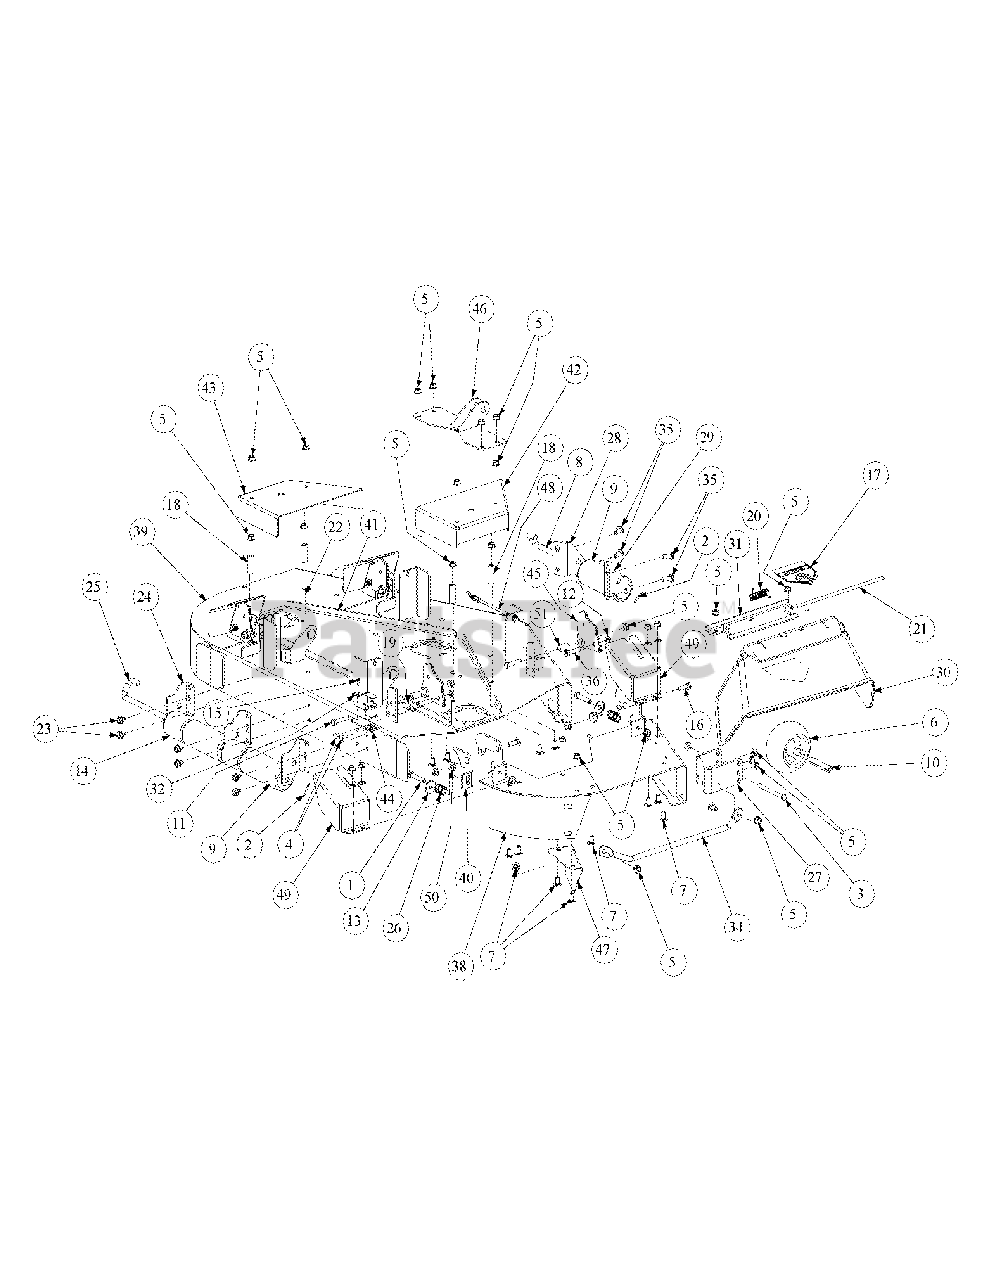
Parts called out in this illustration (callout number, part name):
1	Hex Cap Screw 3/8-16 x 2.00
2	Cotter Pin, .125 Dia. x 1.0
3	Hex Cap Screw, 3/8-16, 3.75
4	Carriage Bolt, 1/4-20 x .750
5	Hex Nut Flange Lock, 3/8-16
6	Complete Wheel, 5.00 Dia
7	Carriage Bolt, 3/8-16 x .75 Lg
8	Roller Pin, 1/2 Dia x 7.31 Lg
9	Front Roller
10	Wheel Spacer
11	Hex Cap Screw, 3/8-16 x 1.750
12	Hex Flange Lock Nut, 5/16-18
13	Flat Washer, .411 x 1.25 x .100
15	Screw, TT, 10-24, .5
16	Carriage Screw, 3/8-16 x 1.25
17	Decal, Danger Hands and Feet
18	Spacer, .39 x .63 x 1.75
19	Nut, 1/4-20, Hex Flange Lock
20	Torsion Spring, 0.4 ID x 2.16 LG
21	Chute Deflector Rod
22	Carriage Bolt, 3/8-16, 2.75
23	Hex Index Washer Screw, 3/8-16, .05
24	Fabricted Deck Roller Mount Bracket
25	Roller Rod
26	Lift Handle Spring
27	Front Anti-Scalp Wheel Mount Bracket
30	Deflector Chute
31	Chute Deflector Bracket
32	Spring Retainer
33	Push Retainer, 3/8
34	Fabricated Deck Finger Guard
35	Self Tapping Screw, 3/8-16 x 0.875
36	Shoulder Bolt 3/8 x 1.50
37	Fab Fold Deck Weldment
38	Fab Fold Wing Weldment, RH
39	Fab Fold Wing Weldment, LH
40	Pull Fold Hinge Lock
41	Deck Stiffener
42	Belt Cover, RH
43	Belt Cover, LH
44	Handle Control Bracket
45	Lift Cable Bracket Weldment
46	Front Lift Bracket Weldment
47	Chute Baffle
48	Lift Cable
49	Lift Wing Shield
50	Spacer, 1.00 x .38 x .63
51	Pivot Spacer
